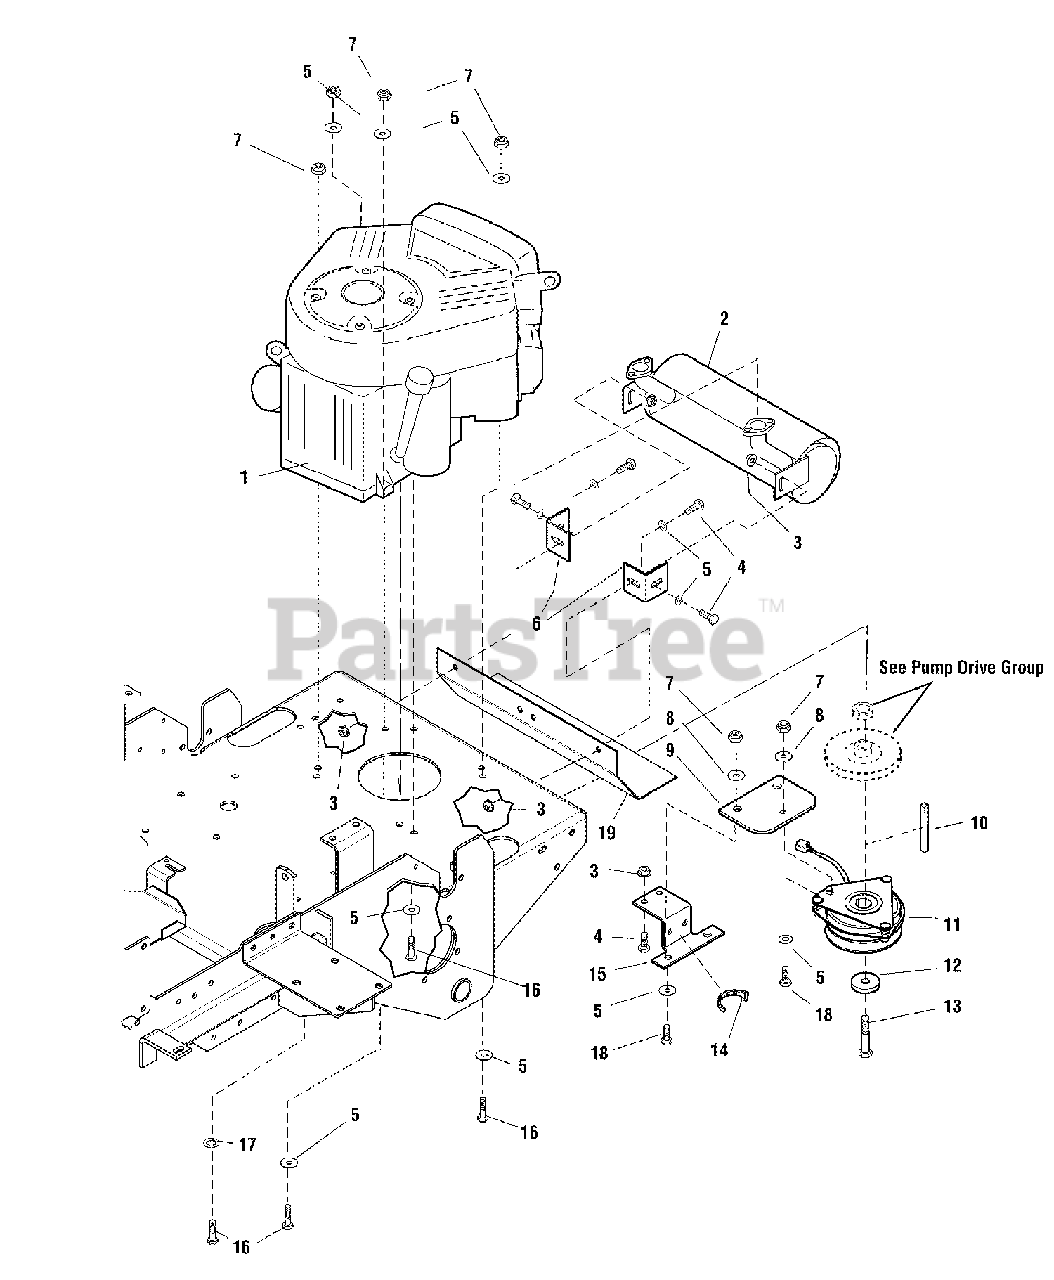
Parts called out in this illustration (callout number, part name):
1	* ENGINE, 20HP B&S Model 358777-0280-E1
2	MUFFLER
3	NUT, HEX NYLOCK FLANGE, 5/16-18
4	BOLT, 5/16-18 X 3/4 GD5
5	WASHER, 5/16" SAE
6	BRACKET, MUFFLER SUPPORT
7	NUT, HEX NYLON LOCK, 5/16-18
8	WASHER, CLUTCH ANCHOR, 5/16
9	CLUTCH ANCHOR PAD
10	KEY, 1/4 SQ. X 2-1/4
11	CLUTCH, ELECTRIC
12	SPACER, .45 X 1.62 X .37
13	BOLT, CRANKSHAFT, 7/16 X 3-1/4
14	CABLE TIE, 12
15	CLUTCH ANCHOR
16	BOLT, 5/16-18 X 1-3/4
17	WASHER, 5/16 INT TOOTH LOCK
18	BOLT, 5/16-18 X 1
19	PLATE, HEAT SHIELD
